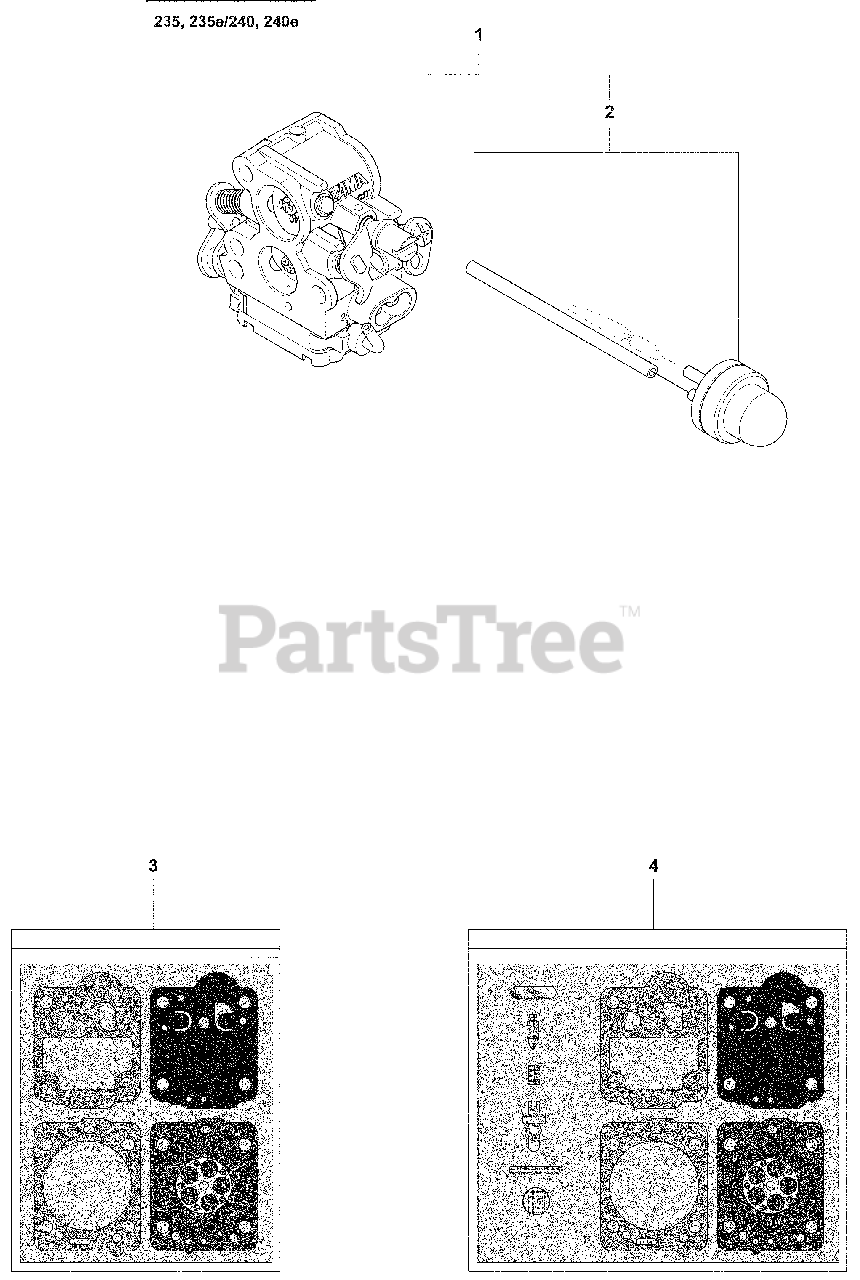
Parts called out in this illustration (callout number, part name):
1	Carb complete
2	Purge and line assembly
3	Kit carb gasket
4	Kit carb repair
